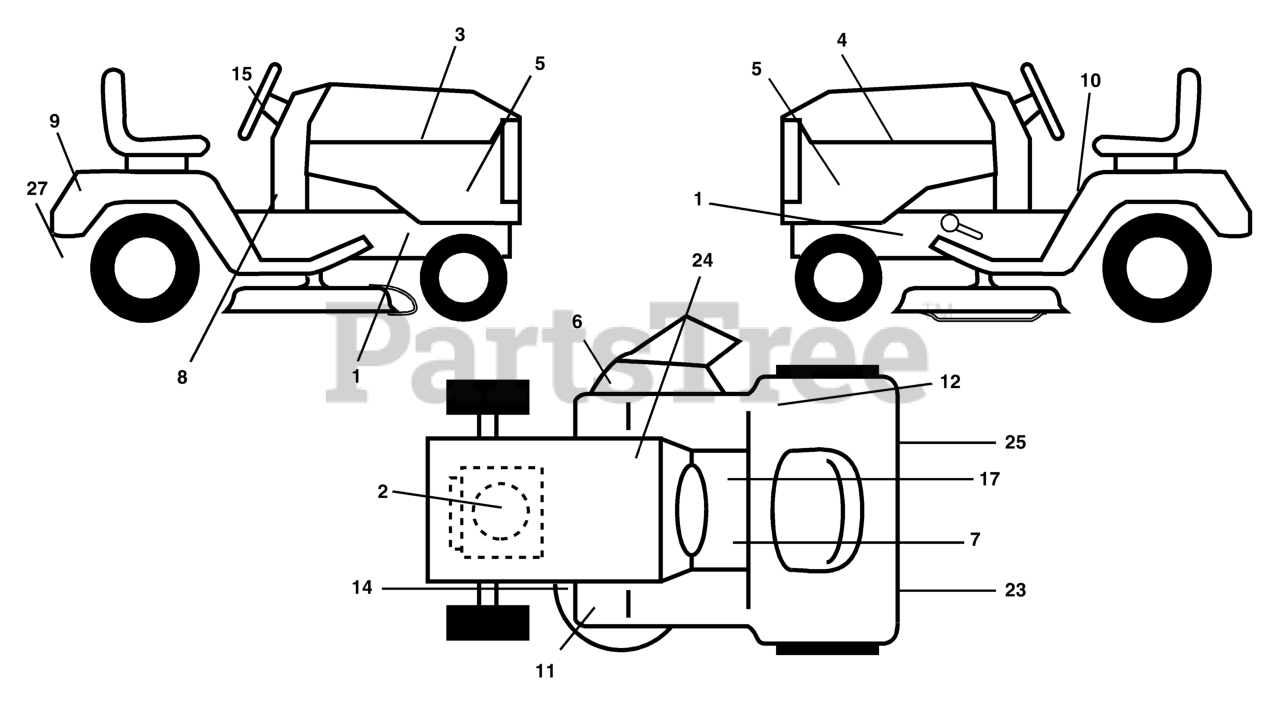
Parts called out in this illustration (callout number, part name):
2	Decal, Engine
3	Decal, Hood, RH
4	Decal, Hood, LH
5	DECAL PNL SIDE
6	DECAL MOWER CUT/FINGER
8	Decal, Dash
9	DECAL, FENDER
10	DECAL READ OWNER'S MAN SYMS
11	Decal, Foot Rest
14	DECAL V-BELT SCHEMATIC
15	DECAL.WHEEL.STEERING.HUSQ.PERM
17	DECAL PARK BRAKE
23	REFLECTOR, LH
24	DECAL BTRY SYMBOLS
25	REFLECTOR, RH
27	DECAL.BYPASS.FENDER.CRD.LT.YT
